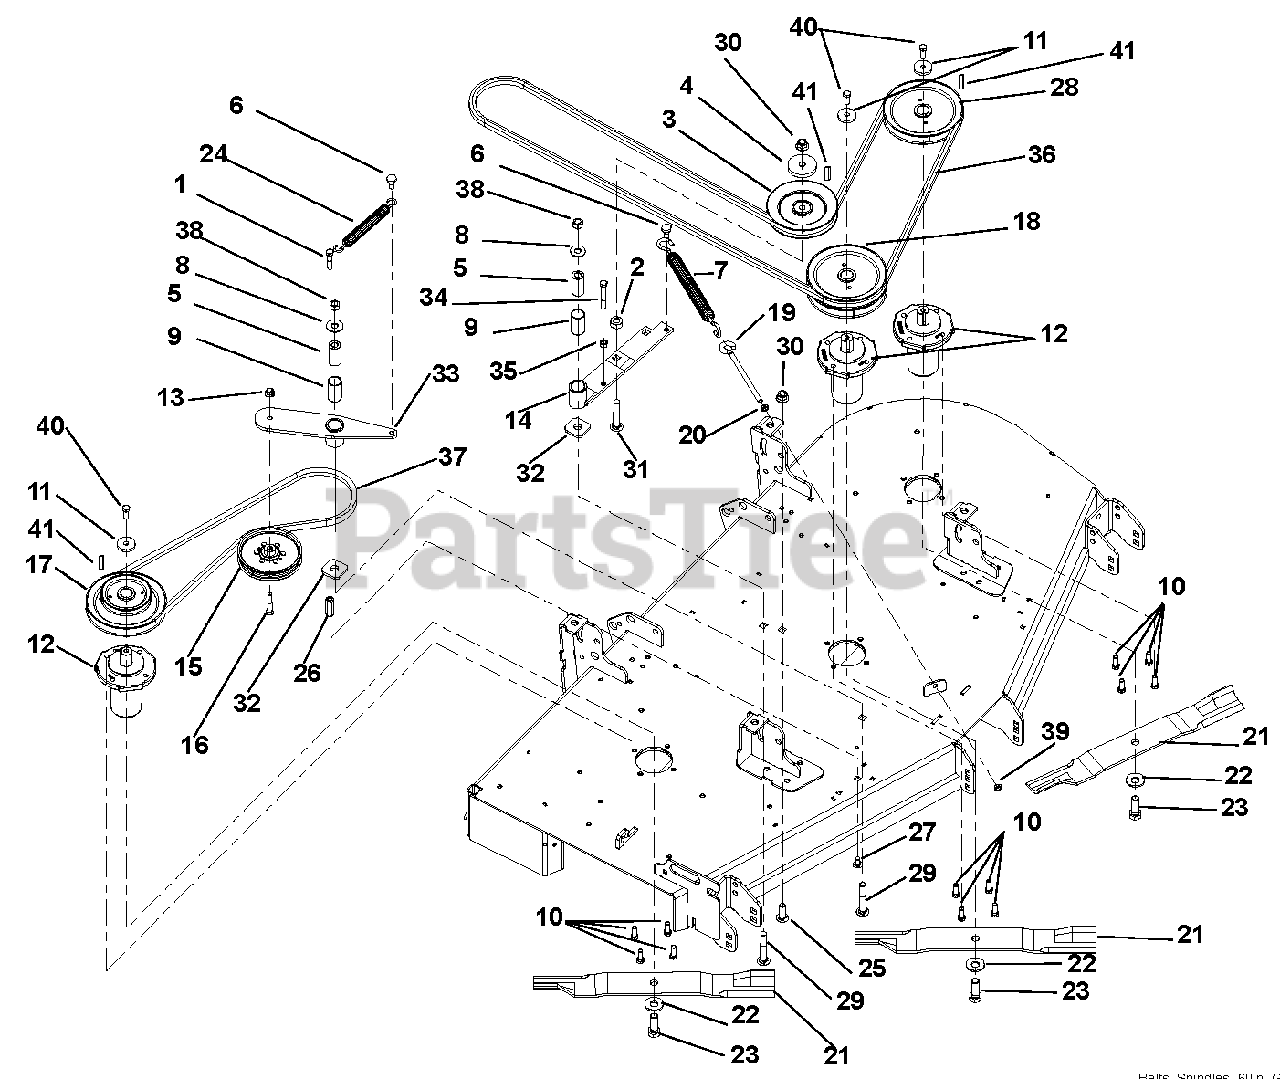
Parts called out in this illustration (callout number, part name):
1	Bolt, Hex .38-16 x 1.50
2	Bushing, Spacer .502 x .997 x .50
3	Sheave, .50" ID x 6.00" OD V-Idler
4	Cap, Idler Bearing Sealing
5	Bushing, Spacer .505/.500 x .999/.996 x 2.05/2.03
6	Bolt, Shoulder EP .38-16 x .30 Hex
7	Spring, Extension (Deck Idler)
8	Washer, Flat Steel .563 x 1.38 x .109
9	Bushing, 1.00 x 1.125 x 1.936
10	Bolt, Hex .38-16 x 1.00
11	Retainer, Sheave
12	Spindle Assembly
13	Nut, Locking Nylon Flange .38-16
14	Weldment, Idler Arm
15	Pulley, Flat Idler Engine to Deck
16	Bolt, Hex .38-16 x 2.00
17	Pulley, Double 1" ID x 6.75" & 4.25" OD
18	Pulley, Double 1" ID x 6.75" OD
19	Bolt, .38-16 x 5.50 .62 Diameter Eye
20	Nut, Hex Jam .375-16
21	Blade, 20.50" Mower
22	Washer, Bellville .63 x 1.625 x.14
23	Bolt, Hex .62-18 x 1.75 Grade 8 (Torque to 115-125 ft. lbs., 155 – 169 N-m)
24	Spring, Extension
25	Bolt, Round Head Square Neck .50-13 x 1.5, Full Thread
26	Nut, Coupling .375-16 x 1.75
27	Bolt, Round Head Square Neck .38-16 x 1.00
28	Pulley, V, 1" ID x 6.75" OD
29	Bolt, Round Head Square Neck .50-13 x 3.25
30	Nut, .50-13 Nyloc Flange
31	Bolt, Round Head Square Neck .50-13 x 3.00
32	Washer, Flat .640 x 1.75 x .250
33	PT160 Deck Idler Arm Weldment, Black
34	Bolt, Hex .38-16 x 2.75
35	Nut, Hex .38-16
36	Belt, 133.00 Wrapped Hex
37	Belt, B 63.00 Raw Cogged
38	Nut, Locking Center .50-13
39	Nut, Lock Center Jam .375-16
40	Bolt, Hex .38-16 x 2.75 Grade 8
41	Key, Square .25 x .25 x 1.00
